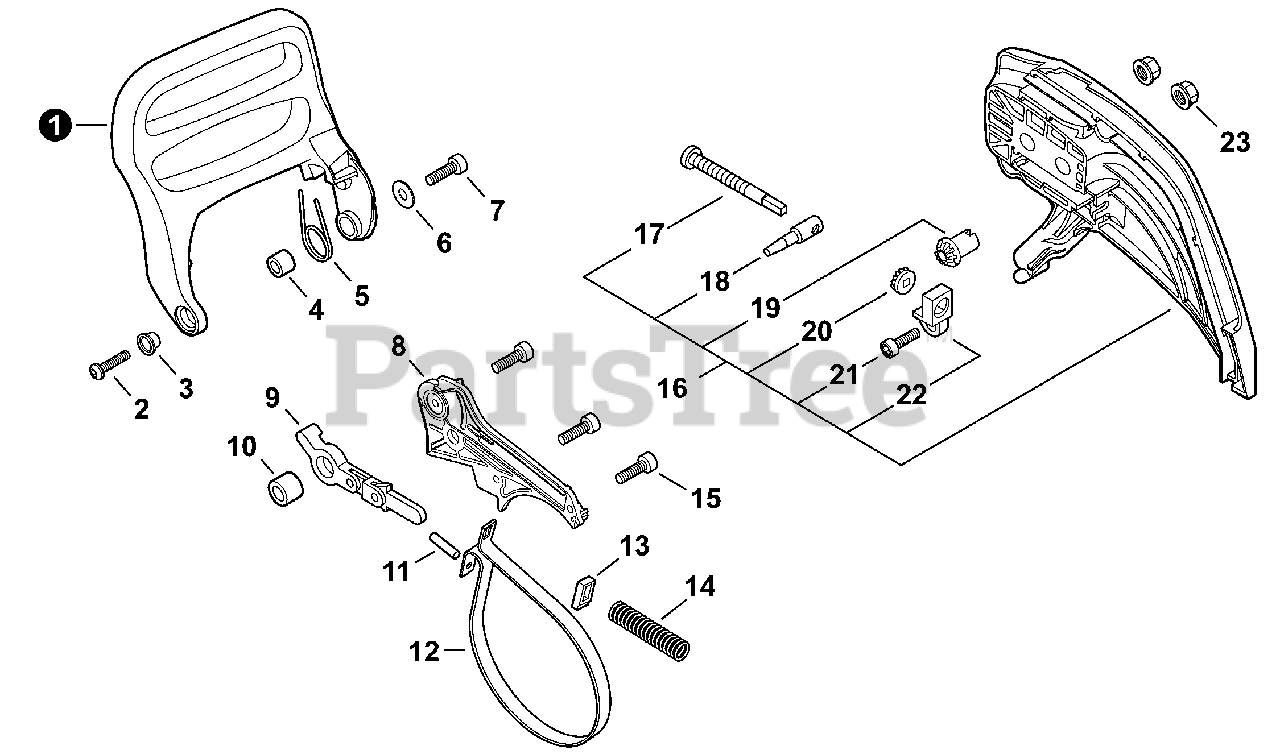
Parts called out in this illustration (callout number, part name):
1	LEVER, BRAKE
2	BOLT, TORX 5×20
3	COLLAR 10
4	SPACER 8×12×9
5	SPRING, TORSION
6	WASHER 4.2×16.5×1
7	BOLT, TORX 4×20
8	COVER, BRAKE
9	CONNECTOR, BRAKE
10	SPACER 8×12×9
11	PIN, SPRING 3×9.8
12	BAND, BRAKE
14	SPRING, COMPRESSION
15	BOLT, TORX 4×12
16	COVER ASSY, CLUTCH
17	SCREW, CHAIN TENSION
18	TENSIONER, CHAIN
19	GEAR, BEVEL
20	GEAR, BEVEL
21	BOLT, TORX 4×12
22	COLLAR 8
